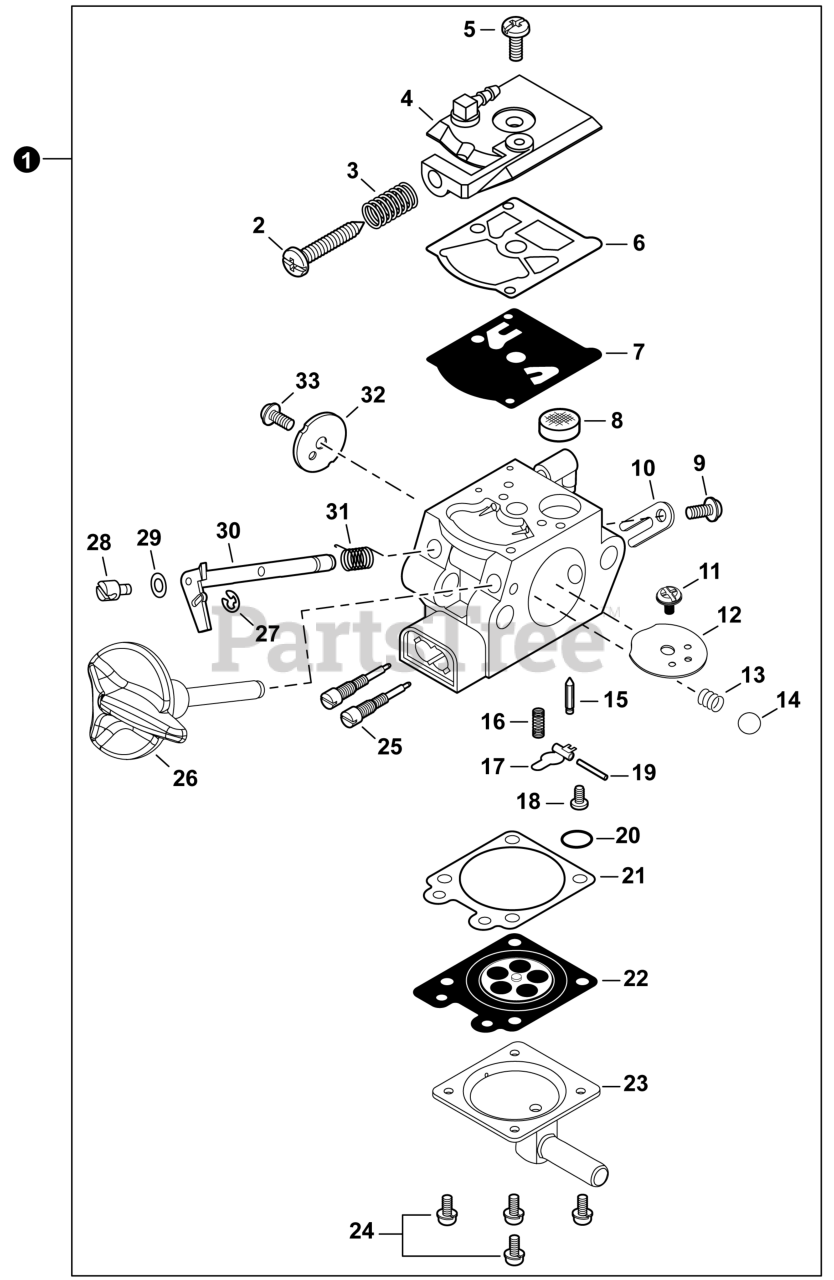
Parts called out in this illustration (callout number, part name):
1	CARBURETOR WT-1096
2	SCREW, IDLE ADJUST
3	SPRING, IDLE ADJUST
4	COVER, FUEL PUMP
6	GASKET, FUEL PUMP
7	DIAPHRAGM, PUMP
8	SCREEN, FUEL INLET
10	CLIP, THROTTLE SHAFT
12	VALVE, CHOKE
14	BALL, CHOKE FRICTION
15	VALVE, INLET NEEDLE
16	SPRING, METERING LEVER
17	LEVER, METERING
18	SCREW, METERING LEVER PIN
19	PIN, METERING LEVER
20	PLUG, WELCH
21	GASKET, METERING DIAPHRAGM
22	DIAPHRAGM, METERING
23	COVER, METERING DIAPHRAGM
25	NEEDLE, MIXTURE
26	SHAFT, CHOKE
30	SHAFT, THROTTLE
31	SPRING, THROTTLE
32	VALVE, THROTTLE
